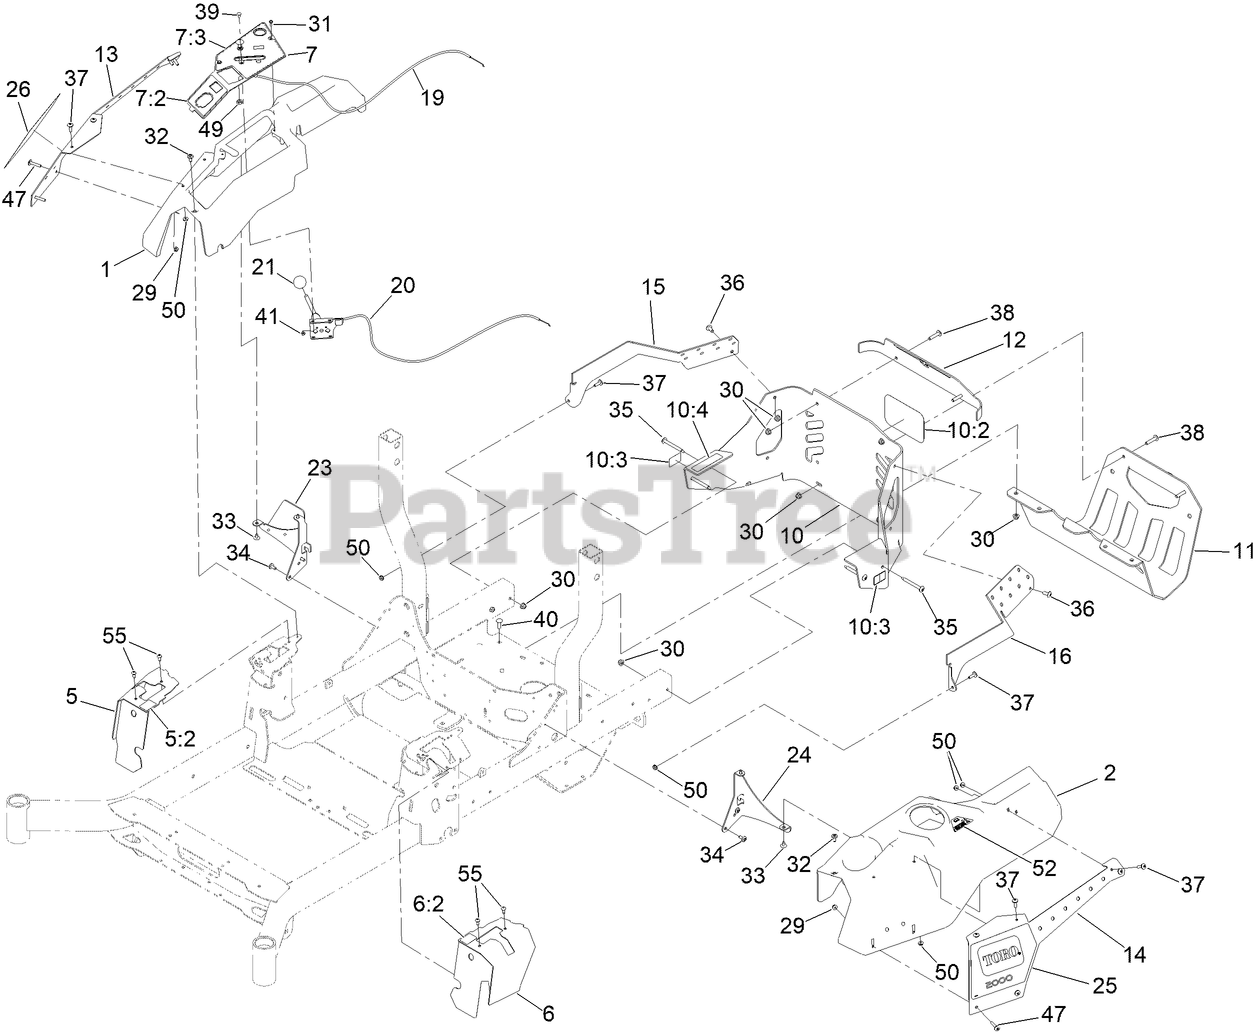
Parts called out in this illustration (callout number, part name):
1	CONSOLE-RH
2	CONSOLE-LH
5	COVER - CONTROL, MOTION
5:2	DECAL-MOTION CONTROL
6	COVER - CONTROL, MOTION
6:2	DECAL-MOTION CONTROL
7	CTRL PANEL ASM
7:2	DECAL-PANEL, CONTROL
7:3	DECAL-PANEL CTRL
10	REAR GUARD ASM
10:2	DECAL
10:3	DECAL-WARNING
10:4	DECAL-ARRESTOR, SPARK
11	GUARD-MUFFLER [BLACK]
12	TRIM-UPPER REAR
13	COVER,POD RH
14	COVER [BLACK]
15	BRACKET-GUARD, RH
16	BRACKET-GUARD, LH
19	CABLE-CONTROL, CHOKE
20	CABLE-CONTROL, THROTTLE
21	KNOB-BALL
23	SUPPORT-CONSOLE, RH
24	BRACKET-CONSOLE, LH
25	DECAL-2000, LH
26	DECAL-2000, RH
29	NUT-HF
30	NUT-HF, NI
31	SCREW-HWH
32	SCREW-SHOULDER
33	SCREW-TORX
34	SCREW-TORX
35	SCREW-TORX
36	SCREW-TORX
37	SCREW-TRUSS
38	SCREW-TORX
39	BOLT-CARR
40	SCREW-CARR
41	NUT-LOCK, NI
47	SCREW-TRUSS
49	NUT-HJ
50	NUT-KEPS
52	DECAL-FILL, FUEL
55	SCREW-TPH THD FORM
